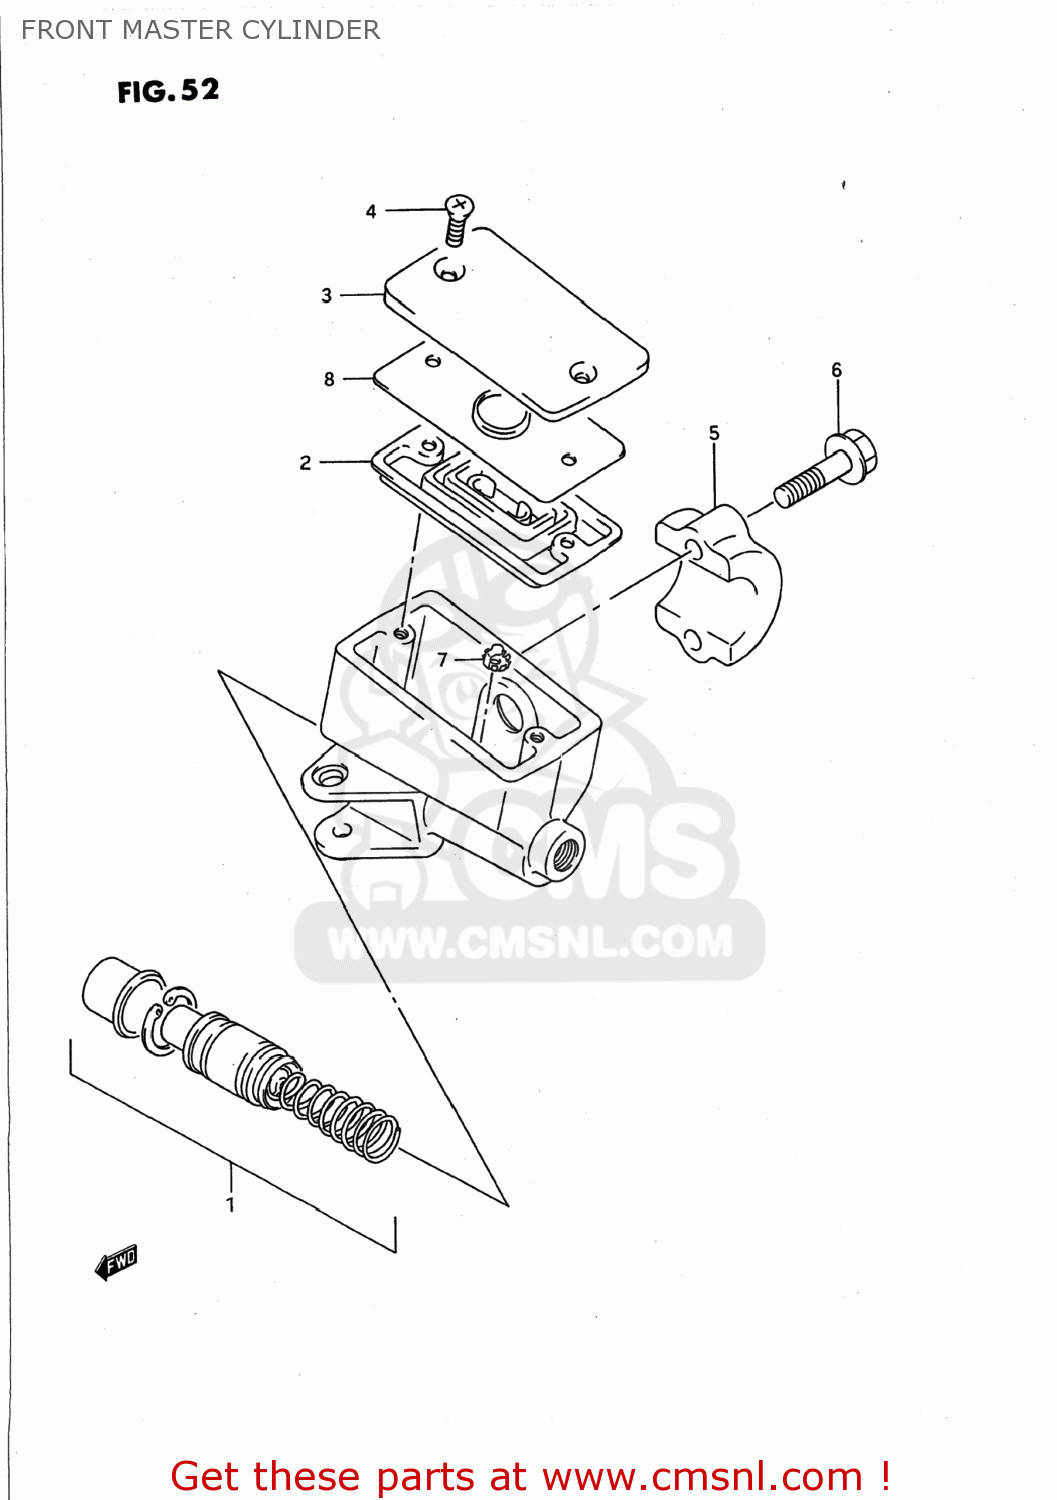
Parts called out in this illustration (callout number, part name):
1	PISTON & CUP SET
2	3-1
3	CAP
4	SCREW
5	HOLDER
6	BOLT(6X25)
7	PROTECTOR
8	PLATE,DIAPHRAGM
